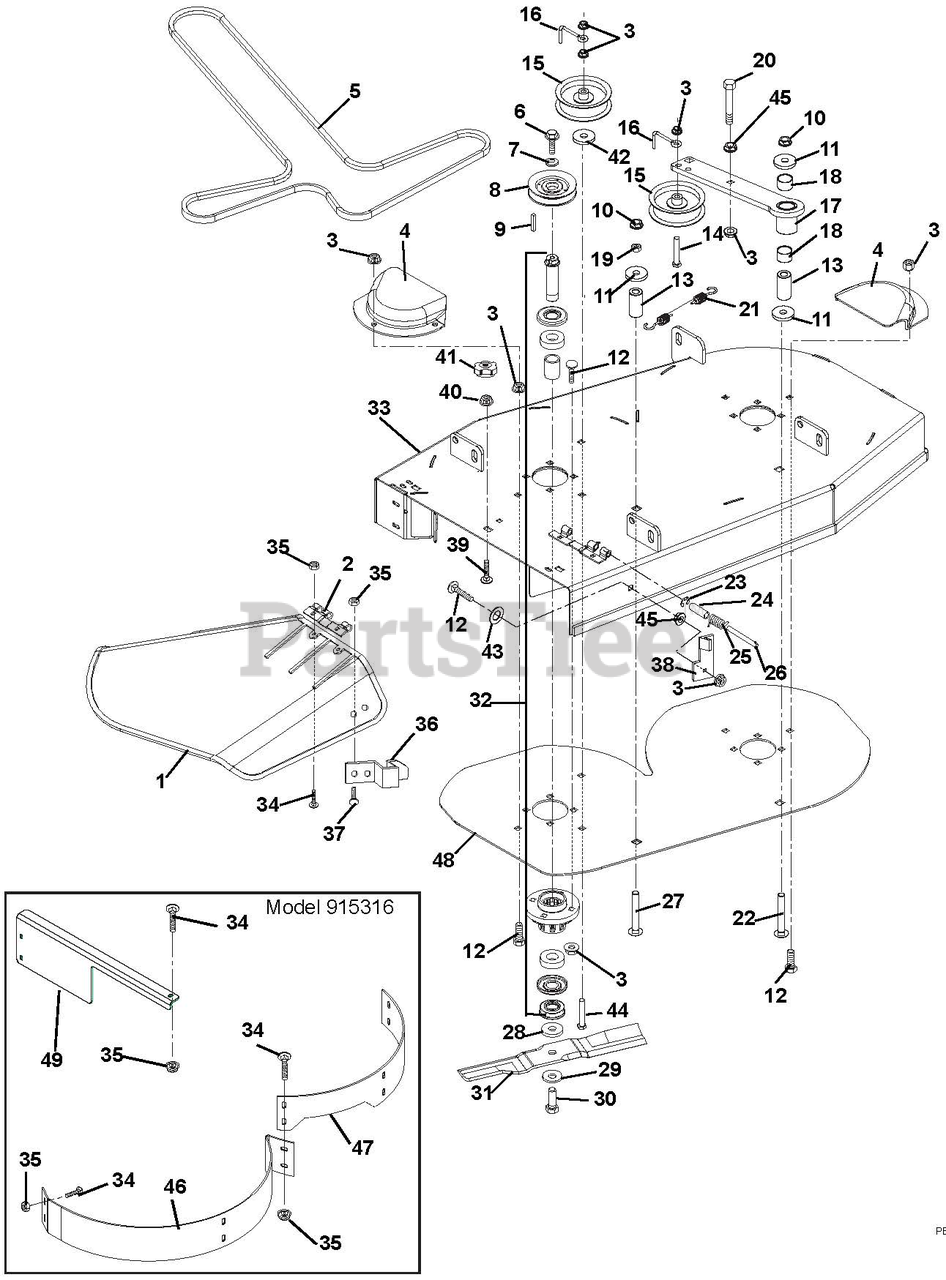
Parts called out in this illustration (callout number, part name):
1	DISCHARGE CHUTE
2	HINGE PLATE
3	@NUT-LK-NYL-FLG .38-16 YWZC
4	BELT COVER
5	V-BELT, HA-WRAPPED
6	BLT-HEX .38-16X1.00 YZ GR8
7	WSHR,FLT STL.406X1.50X.245YWZC
8	SHEAVE, 4.25 DIA A-SECTION
9	KEY, SQ .25 X .38 X .25
10	@NUT-LK-TOP-FLG .50-13 YWZC
11	WSHR-FL-STL .515X1.625X.250 YZ
12	@BLT-RDHDSQNK .38-16X1.25 G5YZ
13	BSHG, SPCR .502X.997X2.03 PM
14	@BLT-HEX .38-16X2.50 GR5 YWZC
15	IDLER FLANGED 3.50
16	FINGER - BELT
17	WMT, IDLER PIVOT ARM
18	BRG, 1.00 X 1.12 X .75
19	NUT-SPNLK-FLG .50-13 YWZC
20	@BLT-HEX .38-16X2.00 GR5 YWZC
21	SG-TENS .187X1.50X9.94 WLD 40
22	@BLT-RDHDSQNK .50-13X3.50 G5YZ
23	RG-RTNG-EXT .312X.025
24	BSHG-SLV .334 X .502 X 1.437
25	SG-TORS .095X.50X 1.0
27	@BLT-RDHDSQNK .50-13X3.75 G5YZ
28	@WSHR-FL-STL.688X1.75X.134 YWZ
29	WSHR-BLVL .669X1.535X.138
30	BLT-HEX .62-18X1.75 GR8 YWZC
31	BLADE
31	BLD,MULCHING 50" MWR
32	ASSEMBLY, SPINDLE
33	34" MZ/MZT DECK
34	@BLT-RDHDSQNK .25-20X.75 G5YZ
35	@NUT-LK-TOP-FLG .25-20 YWZC
36	FLAT SPRING
37	@BLT-RDHDSQNK .25-20X.50 G5YZ
38	BRACKET, CHUTE LOCK
39	BLT-RDHDSQNK .31-18X1.0 SHTYZ
40	@NUT-SPNLK-FLG .312-18 YWZC
41	KNOB-CLAMPING, .312-18 NYLOC
42	SPACER, .39 X 1.50 X .380
43	@WSHR-FL-STL.563X1.38X.109YWZC
44	@BLT-RDHDSQNK .38-16X2.75 G5YZ
45	@NUT-SPNLK-FLG .375-16 YWZC
46	BAFFLE,34"MULCH RH
47	BAFFLE,34"MULCH LH
48	PLATE,34" DOUBLER
49	BAFFLE,CE DISCHARGE
